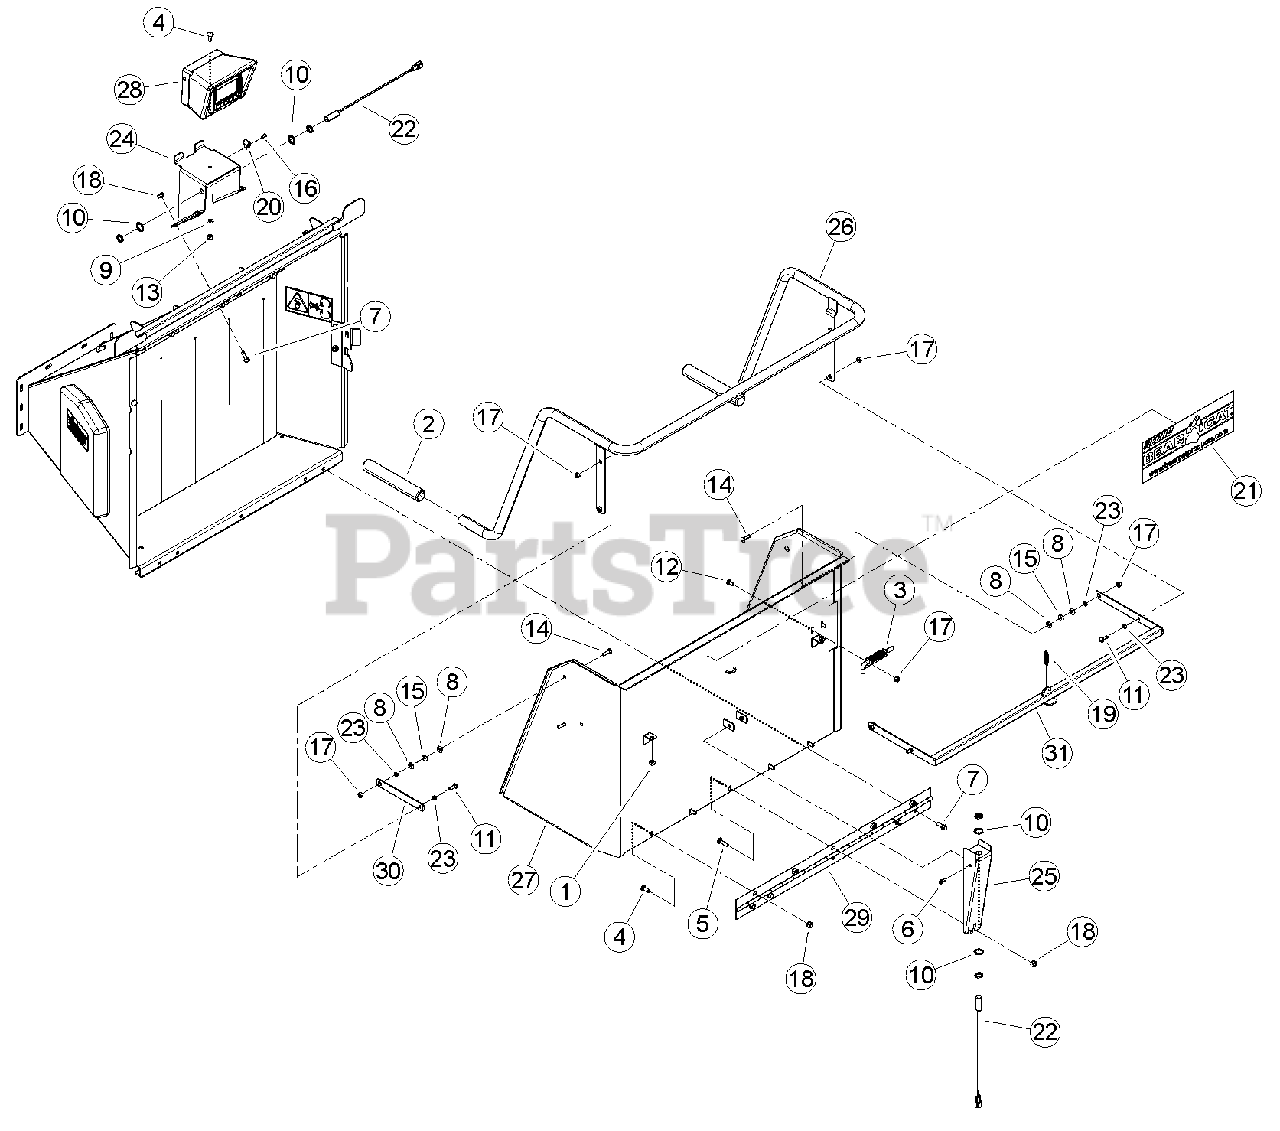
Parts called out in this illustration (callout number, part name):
1	BUMPER, RUBBER
2	GRIP, 1.219 X 10.00
3	LATCH, RH HINGE
4	BOLT, 3/8 X 1" GR5 CRG NC ZP
5	BOLT, 3/8 X 1-1/2" GR5 CRG NC ZP
6	BOLT, 1/4-20 X 3/4 HWH GR5 CZP
7	BOLT, 3/8 X 1 FLANGE NC
8	WASHER, 5/16" FLAT ZP
9	WASHER, 3/8" SAE FLAT ZP
10	WASHER, 3/4 INTERNAL LOCK
11	BOLT, 5/16 X 1" GR5 CRG ZP
12	BOLT, 5/16 X 3/4 GR5 CRG NC ZP
13	NUT, 3/8" NE NYLOCK ZP
14	BOLT, 5/16 X 1-1/4" GR5 CRG ZP
15	WASHER, 5/16" ID 7/8" OD NYLON FLAT
16	RIVET, AL BLIND 1/4 X 3/4 DOME HEAD
17	NUT, 5/16-18 NYLOCK-FLANGE
18	NUT, 3/8-16 NYLOCK FLANGE
19	SPRING, 1/2 X 2.00 LG ZP
20	CLAMP, CABLE MOUNT
21	DECAL, BEARCAT WEB
22	SENSOR, M18 PROXIMITY (REPLACEMENT PART)
23	SPACER, IDLER PIVOT
24	MOUNT, 6" DDC
25	MOUNT, 6" KNEEBAR PROX SENSOR
26	WELDMENT, KNEEBAR 6"
27	WELDMENT, 6" INFEED TRAY
28	ASSEMBLY, DDC ENCLOSURE
29	HINGE, EXTENSION TRAY
30	LINK, PARALLEL
31	WELDMENT, KNEEBAR PIVOT
